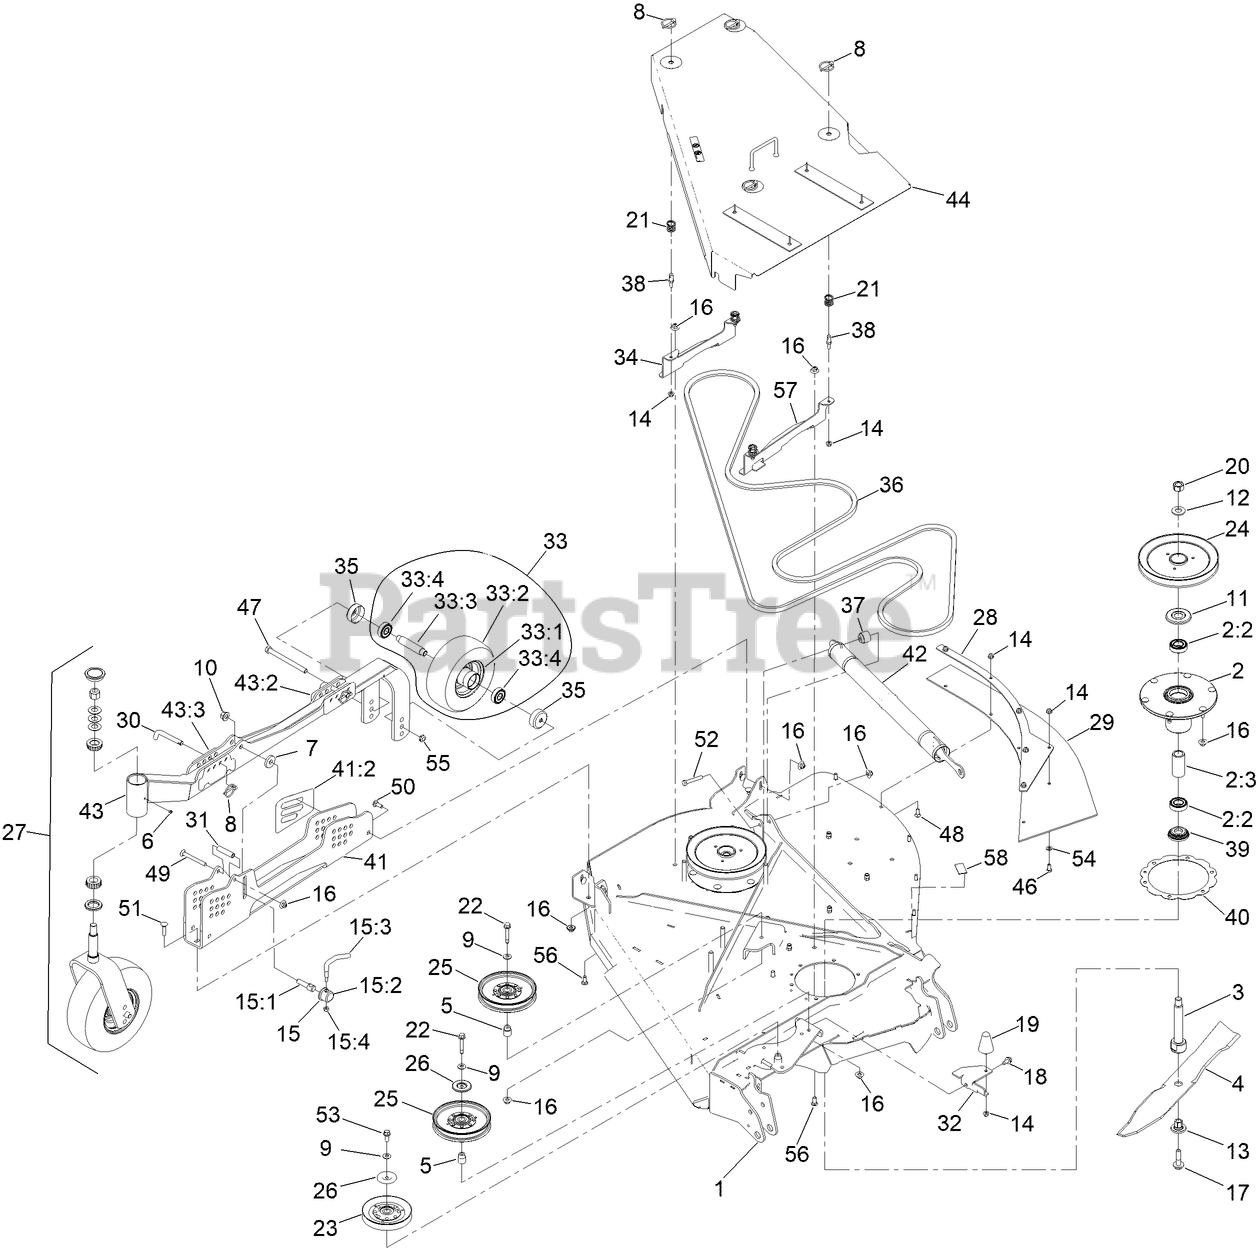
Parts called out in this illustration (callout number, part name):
1	ASM-RH WING DECK 144
2	SPINDLE ASM
2:2	BEARING-BALL
2:3	SPACER-BEARING
3	SHAFT-SPINDLE
4	BLADE-24.50 MULCH
5	BUSHING-IDLER
7	WASHER
8	PIN-LYNCH
9	WASHER-BELLEVILLE
10	NUT-LOCK
11	GUARD-BEARING, TOP
12	WASHER
13	BUSHING-HEX
14	NUT-HF, NI
15	LEVER ASM
15:1	SCREW-LOCK
15:2	CAP-LOCK
15:4	NUT-LOCK, NI
16	NUT-FLANGE, NI
17	SCREW-SEMS
18	SCREW-HWH
19	BUMPER-RUBBER
20	NUT-HEX
21	SPRING
22	SCREW-HHF W/ PATCH
23	IDLER-V
24	SHEAVE-DRIVE, BLADE
25	IDLER-PULLEY
26	SHIELD-DUST
27	CASTER WHEEL ASM
28	SUPPORT-RH REAR GUARD
29	GUARD-RH REAR WING
30	PIN-HOC
31	SPACER
32	BRACKET-COVER RETAINER
33	WHEEL AND TIRE ASM
33:1	WHEEL
33:3	AXLE-CASTER
33:4	BEARING
34	BRACKET-SHIELD MOUNT, OUTER
35	GUARD, SEAL
36	BELT,V-5V-198.75
37	BUSHING-LIFT SPRING
38	PIN, SPRING
39	GUARD-BOTTOM
40	RING-SPACER, HOUSING
41	ASM-CHANNEL, HOC RH W/DECALS
41:2	DECAL-HEIGHT OF CUT, RH
42	ASM-WEIGHT-TRANSFER-SPRING
43	ASM-RH GAUGE WHEEL ARM
43:2	PLATE-GUIDE, REAR
43:3	PLATE-GUIDE, FRONT
44	ASM-BELT SHIELD RH
46	SCREW-HH
47	SCREW-HH
48	SCREW-CARR
49	SCREW-CARR
50	BOLT-CARR
51	SCREW-CARR
52	SCREW-HH
53	SCREW-HHF
54	WASHER-PLAIN
55	NUT-HEX
56	BOLT-CARR
57	BRACKET-SHIELD MOUNT, RIGHT LONG
58	PAD-RUBBER
